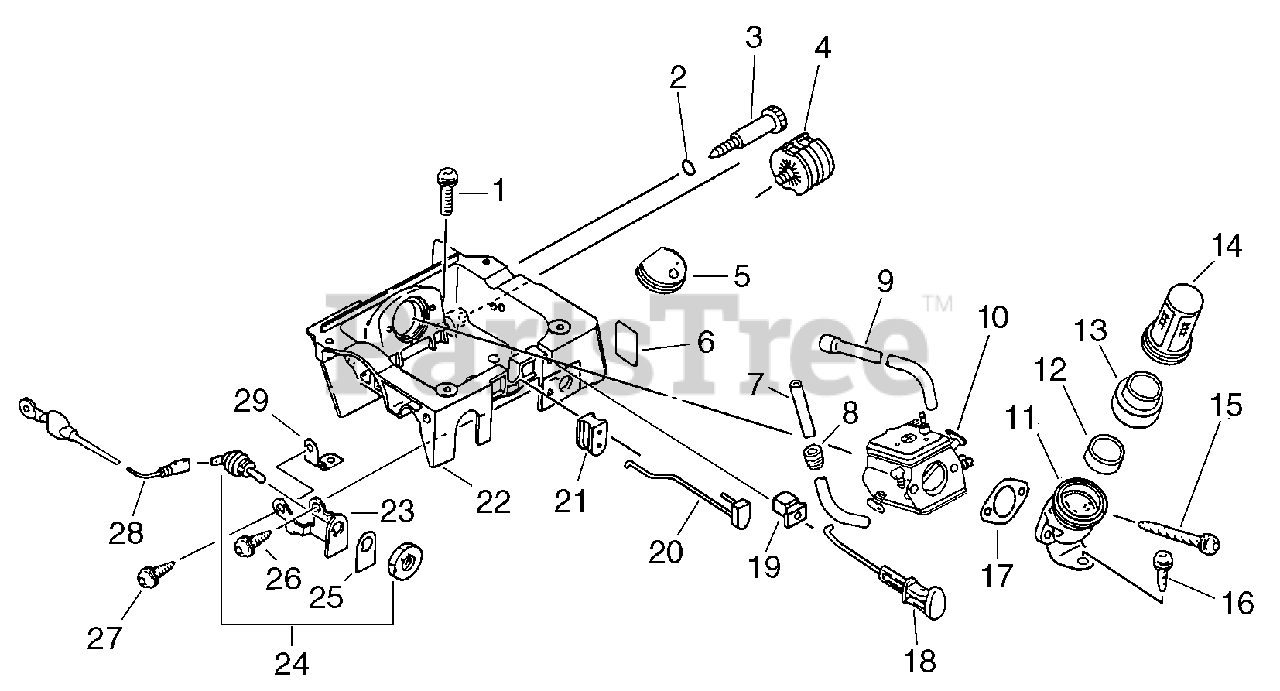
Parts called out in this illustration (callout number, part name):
1	BOLT 5×20
2	O-RING 7
3	SCREW, IDLE ADJUST - GRAY
5	GROMMET, HOSE
6	LABEL, CAUTION - IDLE
7	PIPE, OIL
8	GROMMET
9	PIPE, IMPULSE
10	CARBURETOR - HDA-216
11	MOUNT, AIR FILTER
13	CUSHION
14	SCREEN, FILTER
15	SCREW 5×53
16	SCREW 5×14
17	GASKET, INTAKE
18	ROD, CHOKE
19	GROMMET, CHOKE
20	ROD, THROTTLE
21	GROMMET, THROTTLE ROD
22	CASE, CARBURETOR
23	BRACKET, SWITCH
24	SWITCH, ON-OFF
25	LABEL, SWITCH
26	SCREW 5×10
27	SCREW 4×10
28	LEAD - GROUND
29	PLATE, GROUND
